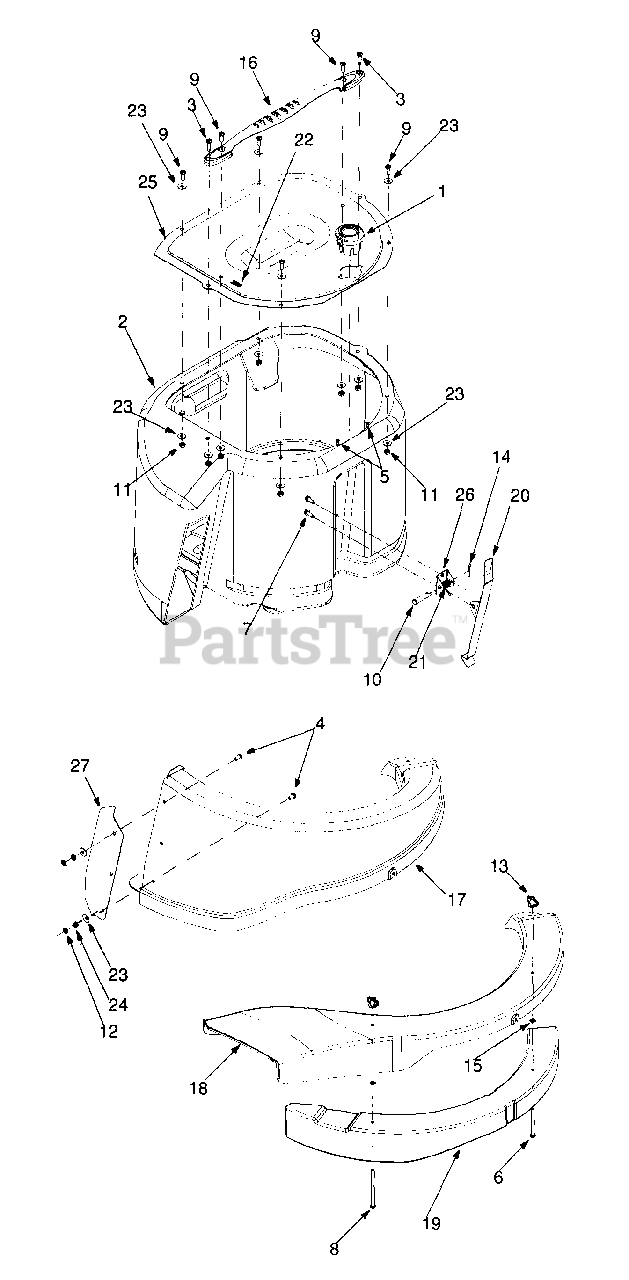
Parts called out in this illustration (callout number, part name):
1	Flow Indicator Assembly
2	Grass Bag Assembly
3	Machine Screw 1/4-20 x 1.0
4	Machine Screw 1/4-20 x 0.5"
5	Hex Screw #10-16 x 0.5"
6	Hex Screw 1/4-20 x 2.75"
7	Self-Tapping Screw 1/4-20 x 0.75"
8	Hex Screw 1/4-20 x 3.75"
9	Machine Screw 1/4-20 x 0.75"
11	Hex Sems Nut 1/4-20
12	Jam Nut
13	Wing Nut
15	Speed Nut
17	Discharge Chute: Grass Bag
18	Side-Discharge Chute
19	Mulching Plug
20	Bag Release Lever
21	Torsion Spring
24	Lock Washer
